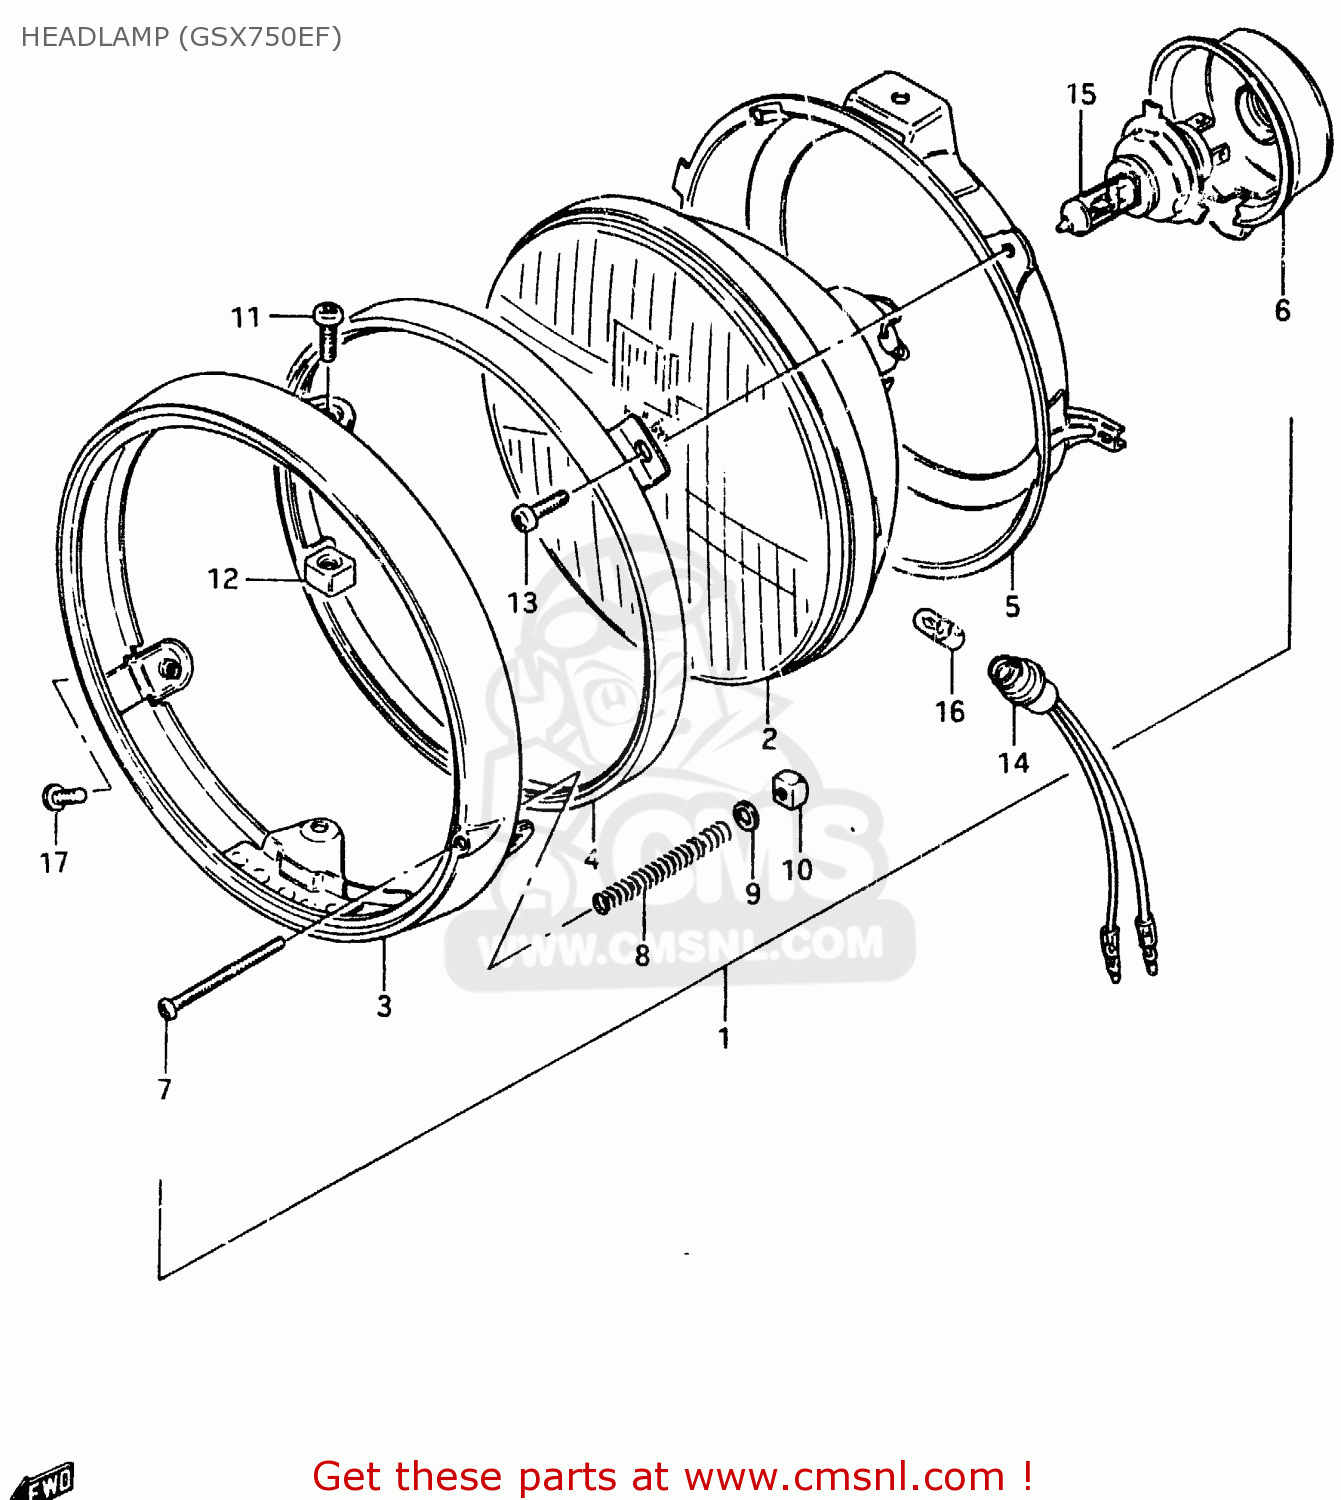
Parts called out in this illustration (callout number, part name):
1	HEADLAMP ASSY
2	UNIT
3	RIM
4	RETAINER
5	RING,MOUNTING
6	COVER,HEADLAMP SOCKET
7	SCREW
8	SPRING,HEADLAMP ADJUST
9	WASHER
10	NUT
11	SCREW
12	NUT
13	SCREW
14	SOCKET,PARKING
15	BULB(12V60/55W,H4)
16	BULB(12V4W)
17	SCREW(5X12)
